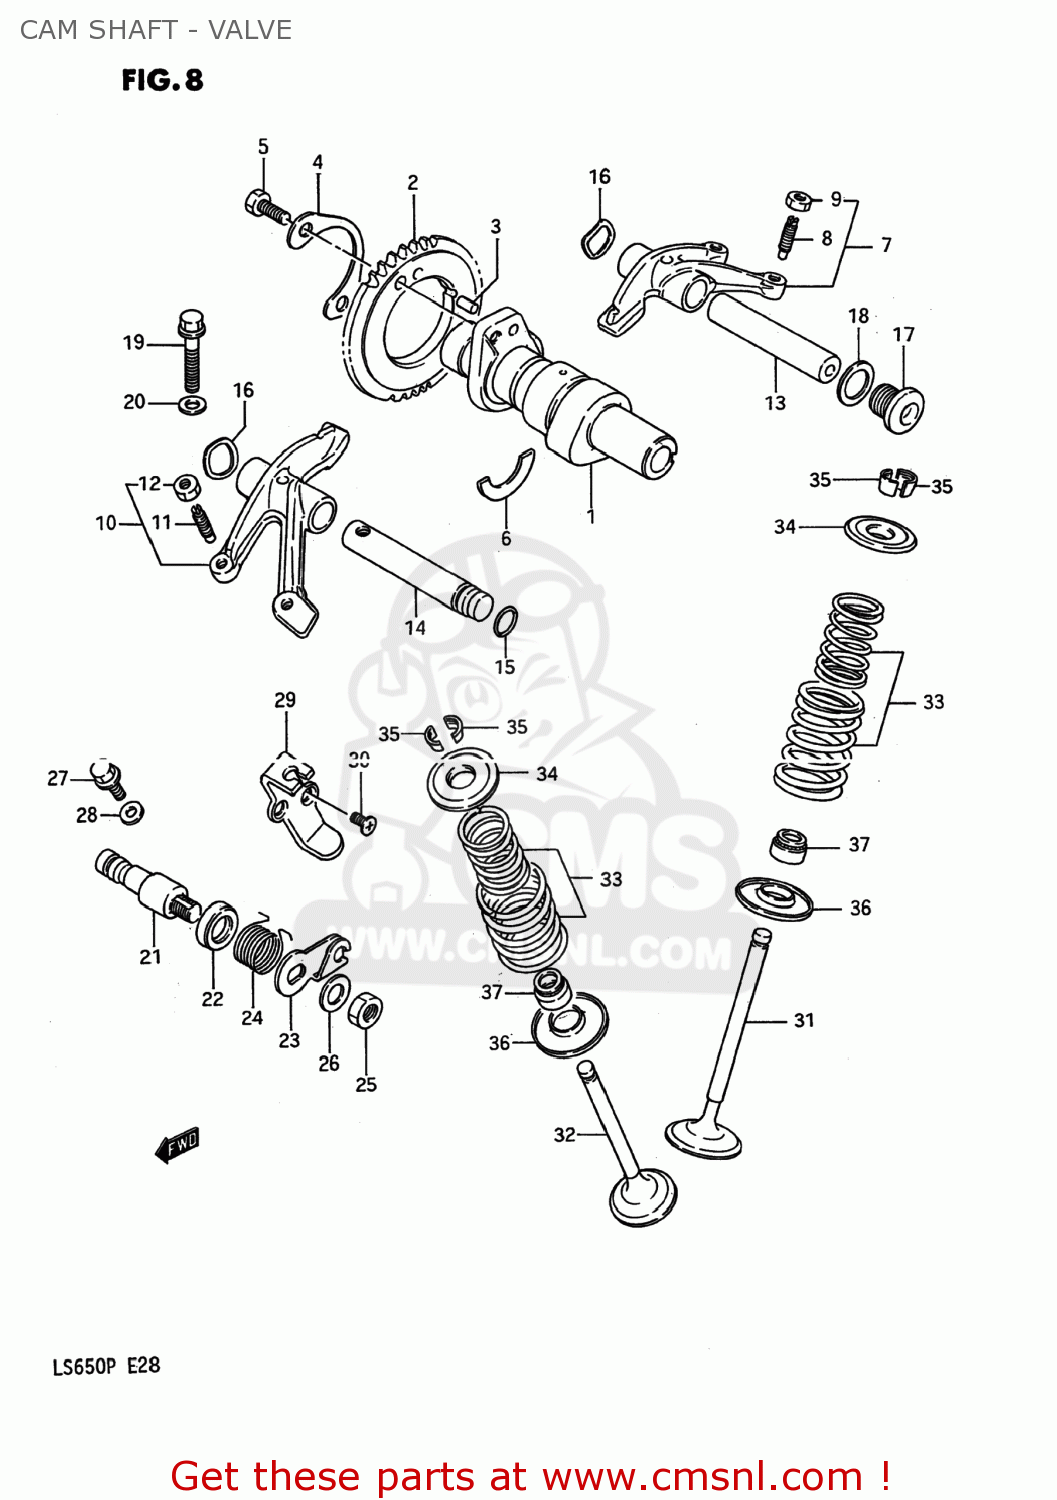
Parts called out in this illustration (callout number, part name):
1	CAMSHAFT
2	SPROCKET,CAMSHAFT
3	PIN(5X12.9)
4	WASHER,CAM CHAIN SPROCKET
5	BOLT(6X16)
6	C RING
7	ARM,VALVE ROCKER
8	SCREW,TAPPET ADJUSTING
9	NUT,ADJUSTING SCREW
10	ARM,VALVE ROCKER,EXHAUST
11	SCREW,TAPPET ADJUSTING
12	NUT,ADJUSTING SCREW
13	SHAFT,VALVE ROCKER ARM INTAKE
14	SHAFT,EXHAUST VALVE ROCKER ARM
15	O RING(D:1.9,ID:8.6)
16	WASHER
17	PLUG
18	GASKET(14X19.2X2) (NAS)
19	BOLT
20	GASKET(5.8X13X1.2) (NAS)
21	SHAFT,DECOMP,L
22	SEAL,OIL(10X20X6)
23	LEVER,DECOMP SHAFT,L
24	SPRING
25	NUT 8MM
26	WASHER
27	BOLT(6X16)
28	GASKET(5.8X13X1.2) (NAS)
29	HOLDER,DECOMP CABLE,L
30	SCREW
31	VALVE,INTAKE
32	VALVE,EXHAUST
33	SPRING SET,VALVE
34	RETAINER,VALVE SPRING
35	COTTER,VALVE
36	SEAT,VALVE SPRING
37	SEAL,OIL(7X14.4X9)
